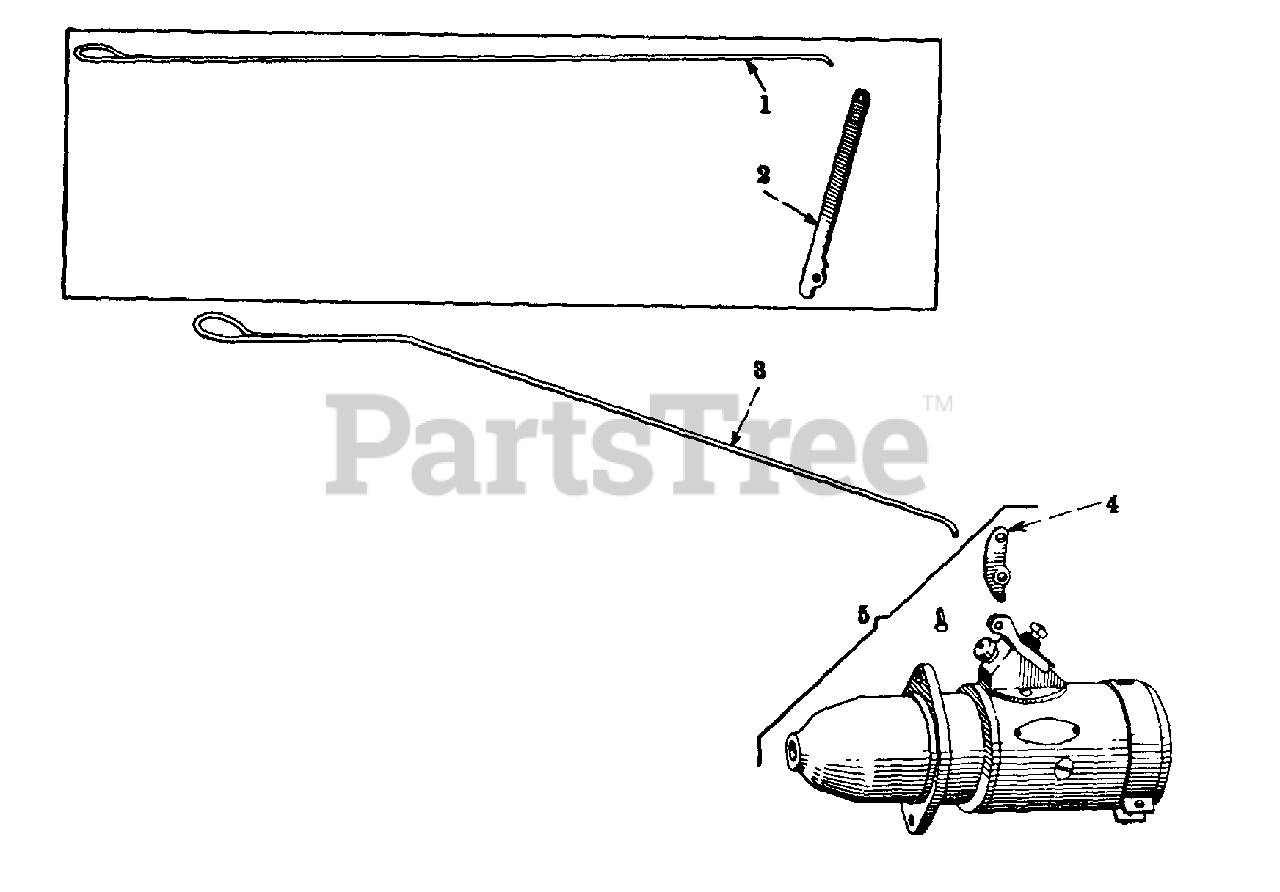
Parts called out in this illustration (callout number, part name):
1	ROD, STARTING SWITCH PULL CUB
2	LEVER, STARTING SWITCH
3	ROD, STARTING SWITCH PULL
4	LEVER STARTING SWITCH
5	MOTOR ASSY, CRANKING
